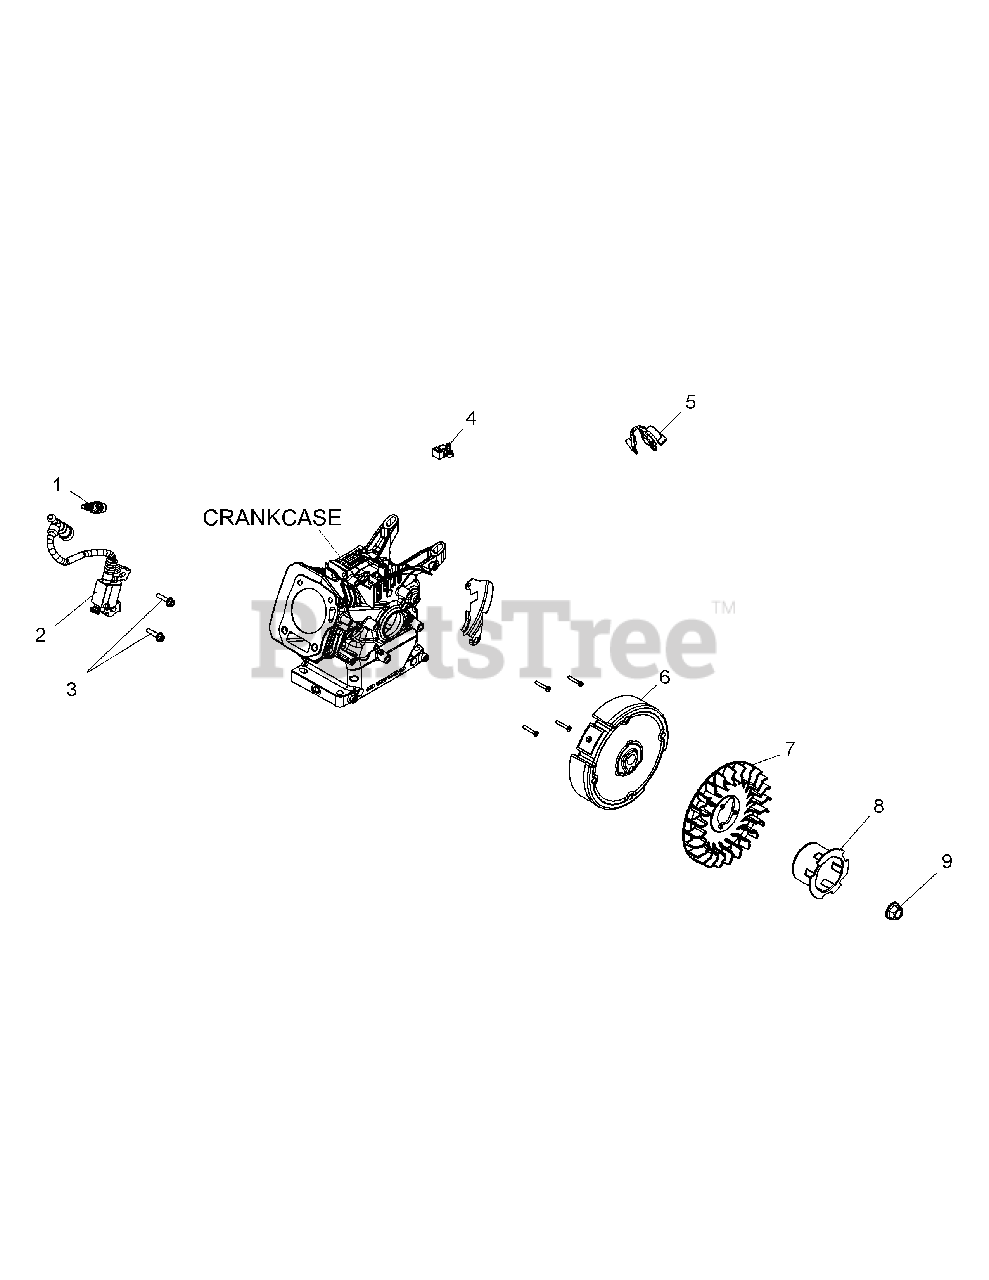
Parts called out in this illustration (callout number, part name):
1	Spark Plug (Std.)
2	Ignition Module
3	Screw, M6 x 25
4	Wire Harness Clip
5	Switch Assembly, On/Off
6	Flywheel Assembly
